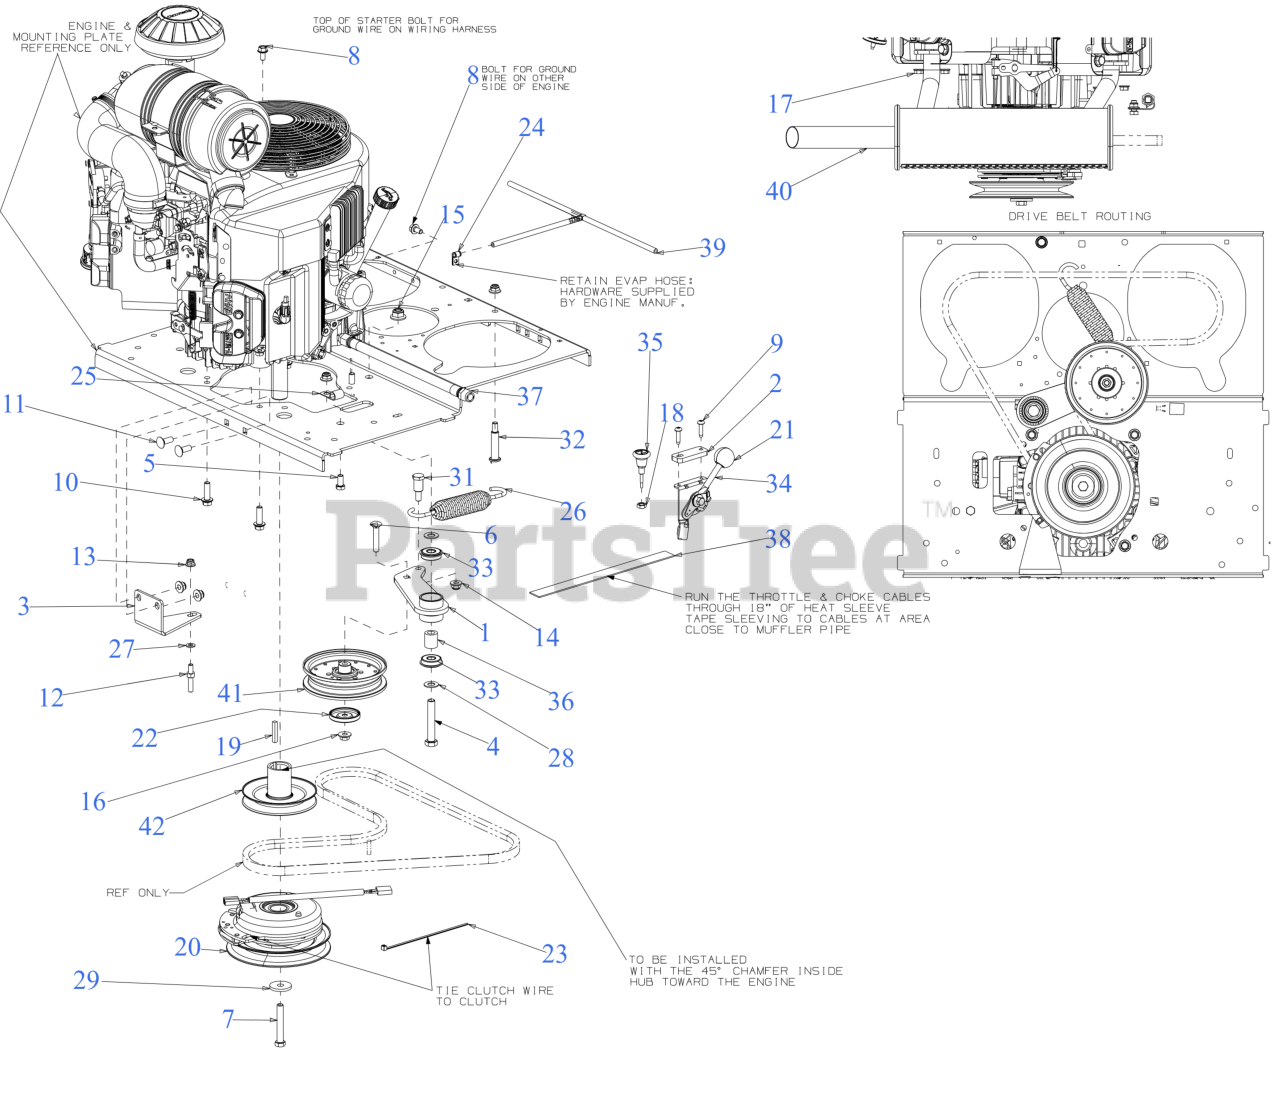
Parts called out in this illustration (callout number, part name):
1	IDLER BRACKET
3	CLUTCH RETAINER BRACKET
4	SCREW-HEX 1/2-13 x 3.00
5	HEX SCREW 3/8-16 x .75
6	CARRIAGE BOLT 3/8-16 x 2
7	SCREW 7/16-20:2.75 GR5
8	SCREW M8 x 1.25 x 16MM GR8.8
9	SCREW 1/4-20 x 1.0
10	SCREW 3/8-16 x 1.25 GR5
11	CARRIAGE BOLT 3/8-16 x 1.00 GR5
13	FLANGE LOCK NUT 5/16-18
16	FLANGE LOCK NUT
17	HEX FLANGE NUT
18	HEX JAM NUT 3/8X24
19	SQUARE KEY 1/4 x 1.50
20	ELECTRIC PTO CLUTCH
22	PULLEY CAP
23	7" CABLE TIE
24	MOUNTING CLAMP
25	J TYPE CLIP
26	EXTENSION SPRING W/HOOK
27	FLAT WASHER
28	FLAT WASHER .510 x .995
29	FLAT WASHER .45 x 1.5 x .172 HT
31	SHOULDER SCREW .625 x .875 x 3/18
32	SHOULDER BOLT (.50 X 2.0 x 3/8 -16)
33	ROLLER BEARING .5X1.37X.44
34	THROTTLE CABLE 59"
35	CHOKE CABLE
36	SPACER 0.51 x 0.88 x 1.00
37	OIL DRAIN HOSE
38	HEAT SHIELD 24"
39	ROLLOVER VENT HOSE ASSEMBLY
40	KAWASAKI MUFFLER
41	FLAT IDLER PULLEY
42	ENGINE PULLEY 5.425
